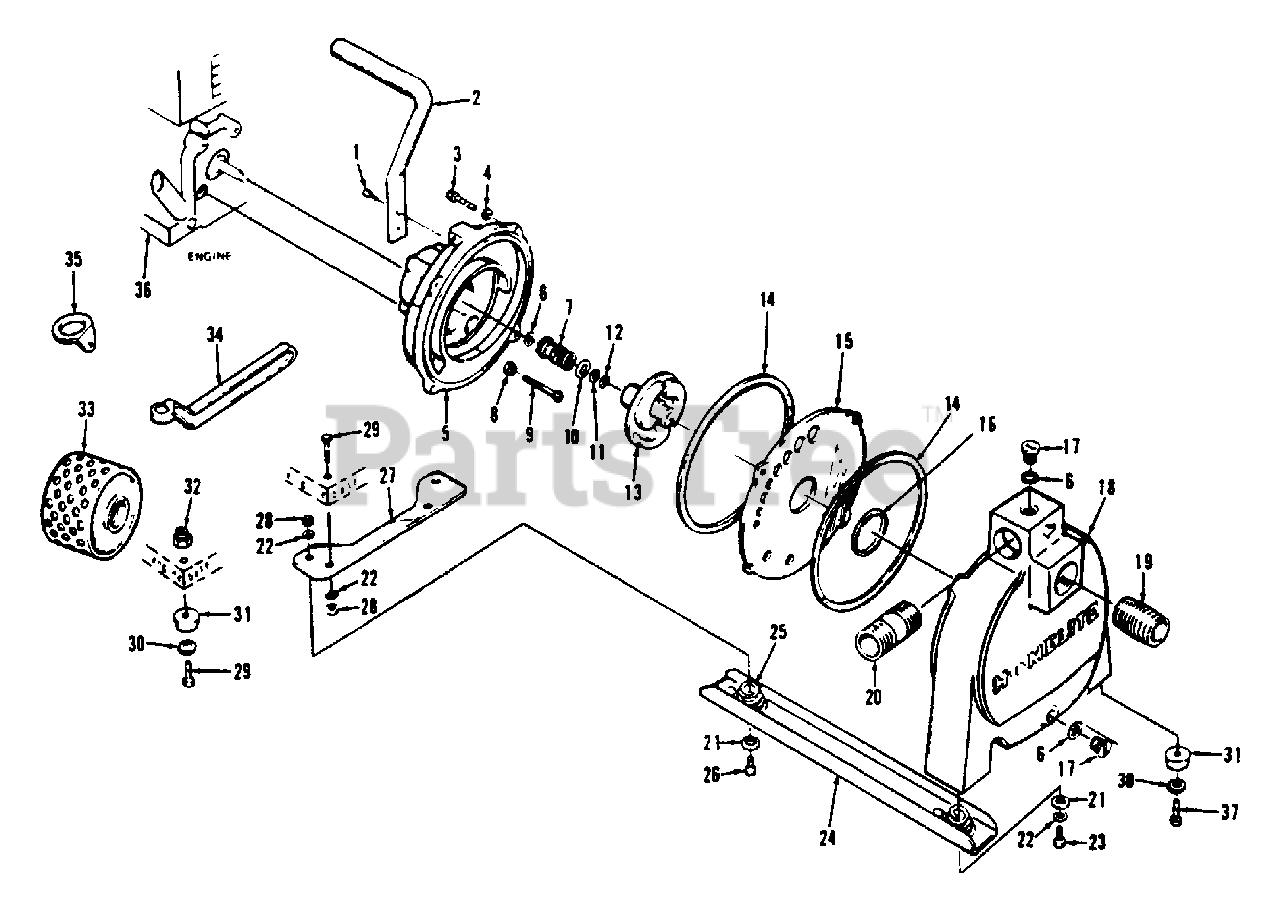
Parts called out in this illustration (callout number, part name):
1	SCREW-lock hex, 1/4-20 x 1/2
2	HANDLE-carryirg
3	SCREW-slot hex, 1/4-20 x 1
4	WASHER-lock, 1/4
5	HOUSING-impeller
6	WASHER
7	SEAL-pump
8	WASHER-sealing
9	SCREW-slot hex, 5/16-24 x 2-1/4
10	SHIM-seal, .010
11	WASHER-spacer
12	SHIM-impeller, .010
13	IMPELLER
15	PLATE-wear
16	GASKET-impeller housing
17	PLUG-drain
18	HOUSING-end (aluminum)
19	FITTING-suction
20	FITTING-discharge
21	WASHER-flat, 5/16
22	WASHER-lock, 5/16
23	SCREW-5/16-18 x 3/4
25	SPRlNG-foot (ea. assembly)
26	SCREW-hex, 5/16-18 x 1
27	BAR-mounting
28	NUT-5/16
29	SCREW-5/16-18 x 1-1/2
30	WASHER-flat, 5/16
31	FOOT-rubber
32	NUT-lock, 5/16
33	STRAINER
34	WRENCH-spanner
35	BRACKET-wrench holder
36	ENGINE-Briggs & Stratton
37	SCREW-hex hd., 5/16-18 x 5/8
